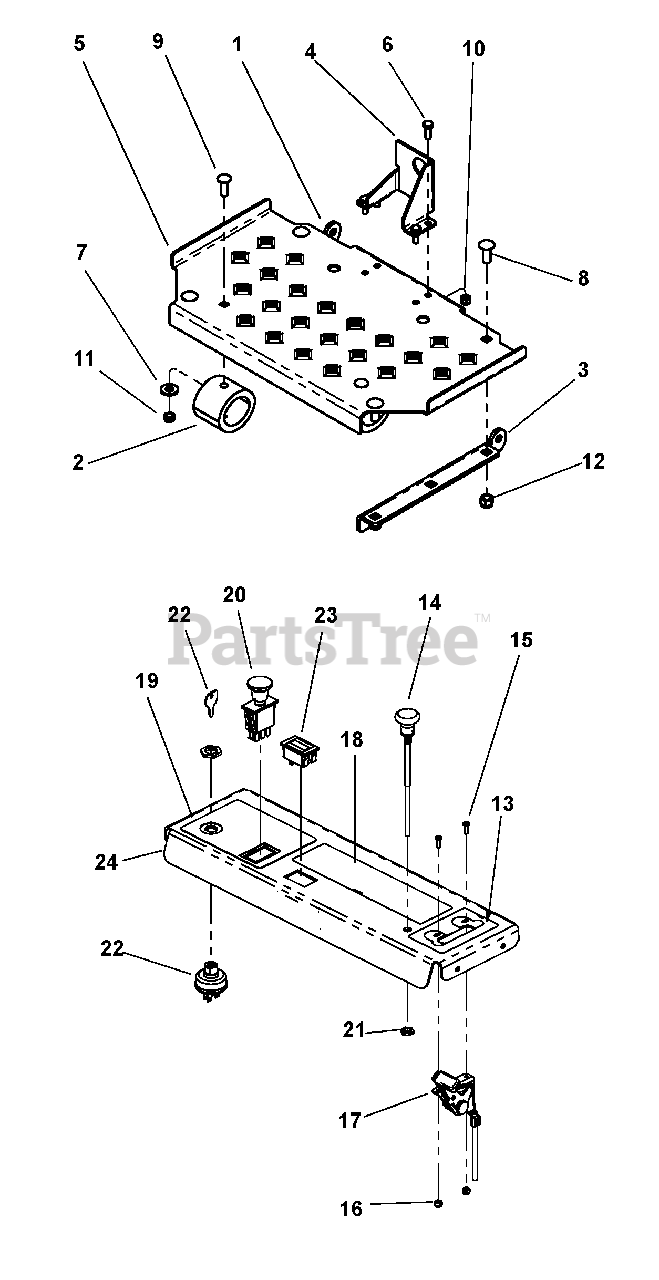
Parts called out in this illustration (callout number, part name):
1	PLATE, PLATFORM TAB
2	BUMPER, MINER GBR-6
3	PLATE, PLATFORM TAB LH
4	ANCHOR, OPC
5	PLATFORM
6	BOLT, 1/4-20X.750 HEX 5 Y
7	WASHER, .313 REG FLAT Y
8	BOLT, 3/8-16X1.00 CRG 5 SN Y
9	BOLT, 5/16-18X1.00 CRG 2 Y
10	LOCKNUT, 1/4-20 NYLOC Y
11	LOCKNUT, 5/16-18 NYLOC Y
12	LOCKNUT, 3/8-16 NYLOC Y
13	DECAL, THROTTLE
14	CABLE, CHOKE
15	@BLT-HEX 8-32 X .5 YWZC
16	#8.32 ELASTIC STOP NUT
17	CABLE, THROTTLE
18	DECAL, GENERAL CAUTION
19	DECAL, PTO/IGNITION
20	SWITCH, PTO ENGAGEMENT
21	NUT-HEX .375-24 YWZC
22	SWITCH, KEY - 3 POSITION
23	METER, HOUR - LCD ALT. (ENM)
24	TOP, CONSOLE
